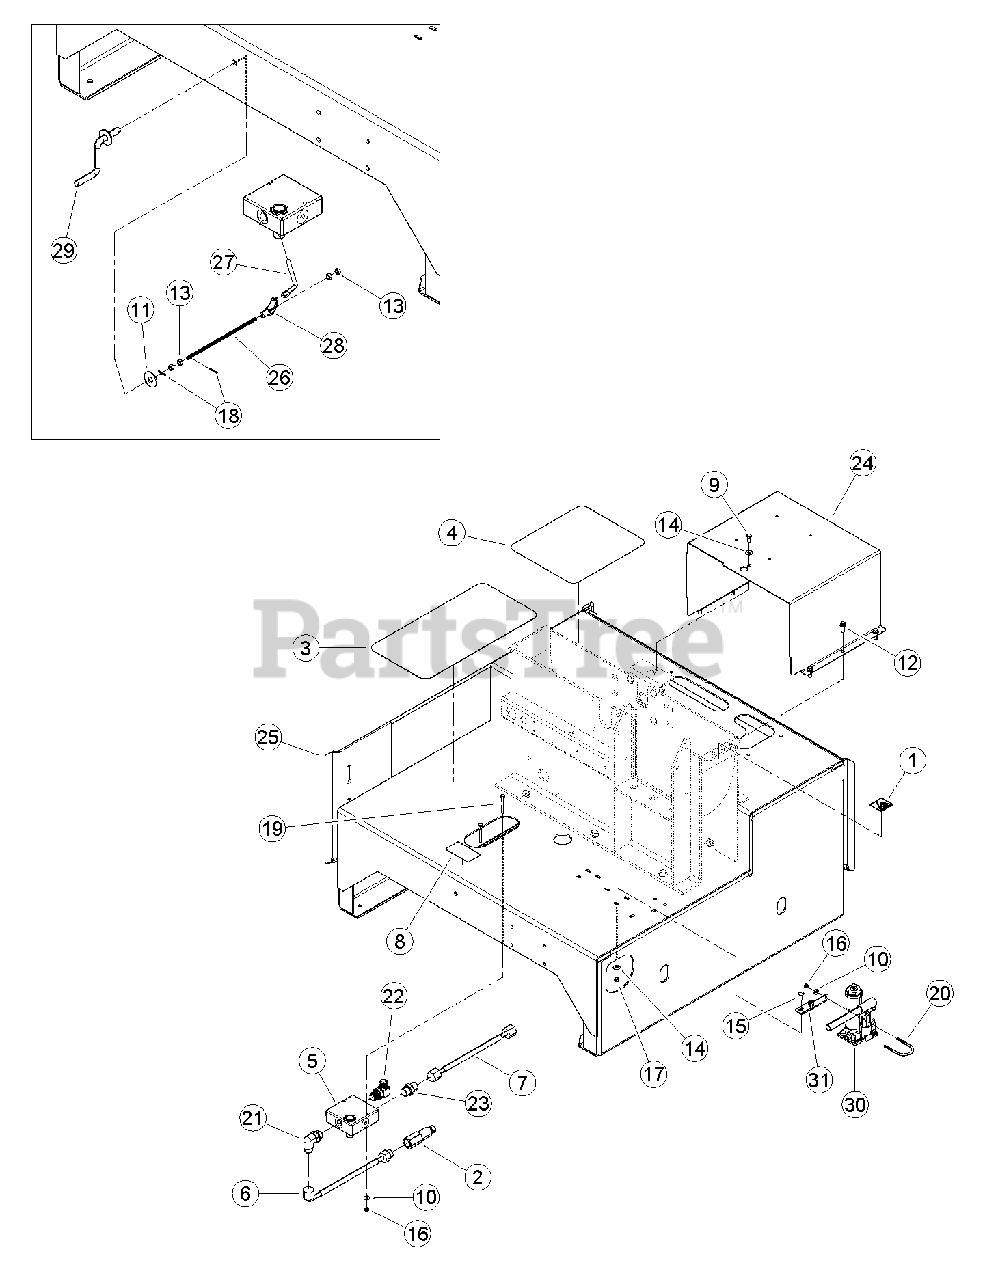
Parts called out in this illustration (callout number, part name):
1	DECAL, SHIELD DANGER ISO
3	TREAD, SAFETY
4	TREAD, SAFETY
5	VALVE, 30 GPM FLOW CONTROL
6	HOSE, .75 X 119 -12 MORING / -12 FMJIC 90 DEG.
7	HOSE, .75 X 40 -12 FMJIC / -12 FMJIC
8	DECAL, FEED SPEED
9	BOLT, 5/16 X 3/4 HEX HD GR5 ZP (CH800H ONLY)
10	WASHER, 1/4 FLAT ZP
11	WASHER, 1/2 FLAT ZP (WAS 15034, REMOVED)
12	SCREW, 3/8-16 X 1 LG THD CUTT ZP
13	NUT, 1/4-28 UNF ZP (WAS 15125, REMOVED)
14	WASHER, 5/16 FLAT ZP
15	BOLT, 5/16 X 7/8 CRG GR5 NC ZP
16	NUT, 1/4 NE NYLOCK ZP
17	NUT, 5/16 NE NYLOCK ZP
18	PIN, 3/32 X 3/4 COTTER (WAS 15380, REMOVED)
19	BOLT, 1/4 X 2-1/2 HEX HD GR5 ZP
20	U-BOLT, 1/4 X 1-1/2 PIPE
21	ADAPTER, -12 MORING / -12 MJIC 90 DEG.
22	ADAPTER, -12 MORING / -10 MJIC 90 DEG.
23	ADAPTER, -12 MORING / -12 MJIC
24	COVER, HYDRAULIC MOTOR (CH800H)
25	WELDMENT, CHIPPER BASE
26	ROD, 1/4-28 THREADED (WAS 73695-00, REMOVED)
27	LEVER, FLOW CONTROL (WAS 73696-00, REMOVED)
28	CLEVIS, FLOW CONTROL (WAS 73697-00, REMOVED)
29	WELDMENT, FEED CRANK (WAS 73713-12, REMOVED)
30	JACK, HYDRAULIC 2 TON
31	PLATE, JACK MOUNT
